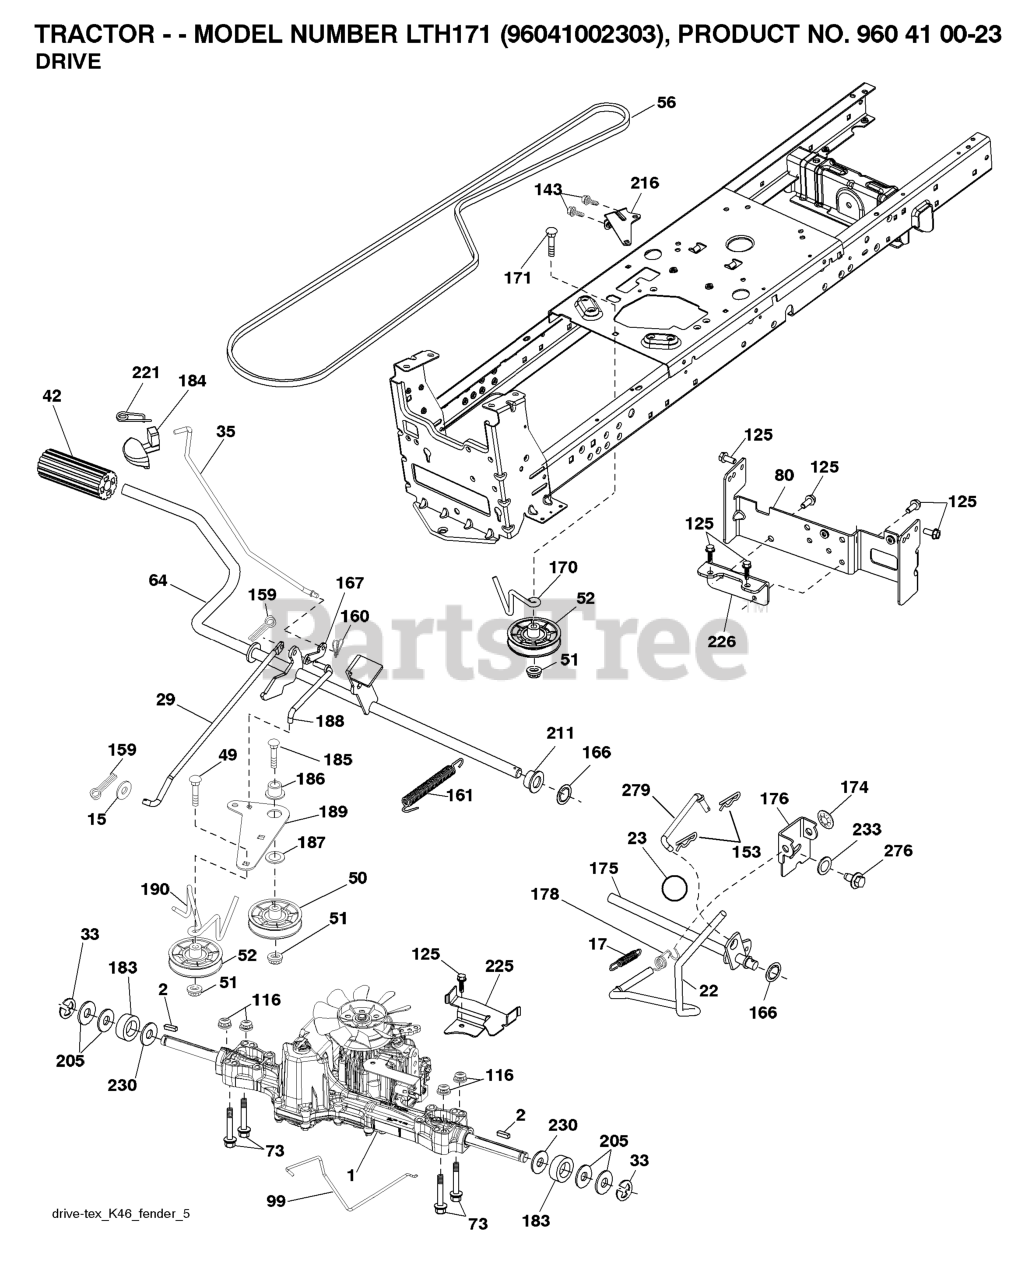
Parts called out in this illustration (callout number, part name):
2	SQUARE KEY
15	WASHER
17	SPRING.BRAKE.K46.GREEN
22	ROD.SHIFT.FENDER.TLT.2006
23	KNOB.DUCKHEAD.1/2
29	ROD.BRAKE.K46
35	ROD.CNTRL.PARK.PREDATOR.LT.TEX
42	PEDAL COVER T
50	IDLER.FLAT.910.OFFSET
51	NUT LOCK FLG 3/8-16 UNC
52	IDLER.V-GROOVE.910.OFFSET
56	V-BELT.MOWER.92.40.42/K46
64	SHAFT.ASM.PEDAL.BRAKE.
73	BOLT HEX 5/16-18 GR 5
80	STRAP TORQUE
99	ROD.SPRING.BYPASS.K46.LT.Z
116	NUT LOCK HEX FLANGE 5/16-18
125	SCREW
143	Screw 5/16-18 x 1/2 Hex, Self Tapping 5/16-18 x 1/2
153	RETAINER M
159	COTTER PIN
160	RETAINER CLIP
161	SPRING, RETURN LT
166	NUT.PUSH.625.2006
167	LATCH.BRAKE.SPRING
170	KEEPER.V-IDLER.CENTER.
174	NUT.PUSH.500.2006
175	SHAFT ASM SHIFT
176	ARM.CLEVIS.ROD.SHIFT
178	SPRING.SHIFT.GT2006
183	SPACER AXLE
184	HANDLE PARKING BRAKE
186	SPACER.RETAINER
187	WASHER 12/32X2X10GA
188	RP.LINK.CLUTCH.GROUND.DRIVE
189	BELLCRANK.GROUND.DRIVE.TEX.
190	KEEPER.BELLCRANK.DRIVE
211	BUSHING.SHAFT.BRAKE.HAND
216	BRACKET.PULLEY.IDLER.W/TEX
221	RETAINER.SPRING.CLIP.H
225	KEEPER.BELT.TRANSAXLE.K46
226	BRACKET.MOUNT.TORQUE.K46.TLT
230	WASHER.HARDENED
233	WASHER SERRATED
276	BOLT FIN HEX 7/16-14 X 1
279	LINK.SHIFT.T/A.K46.FEND.TX
